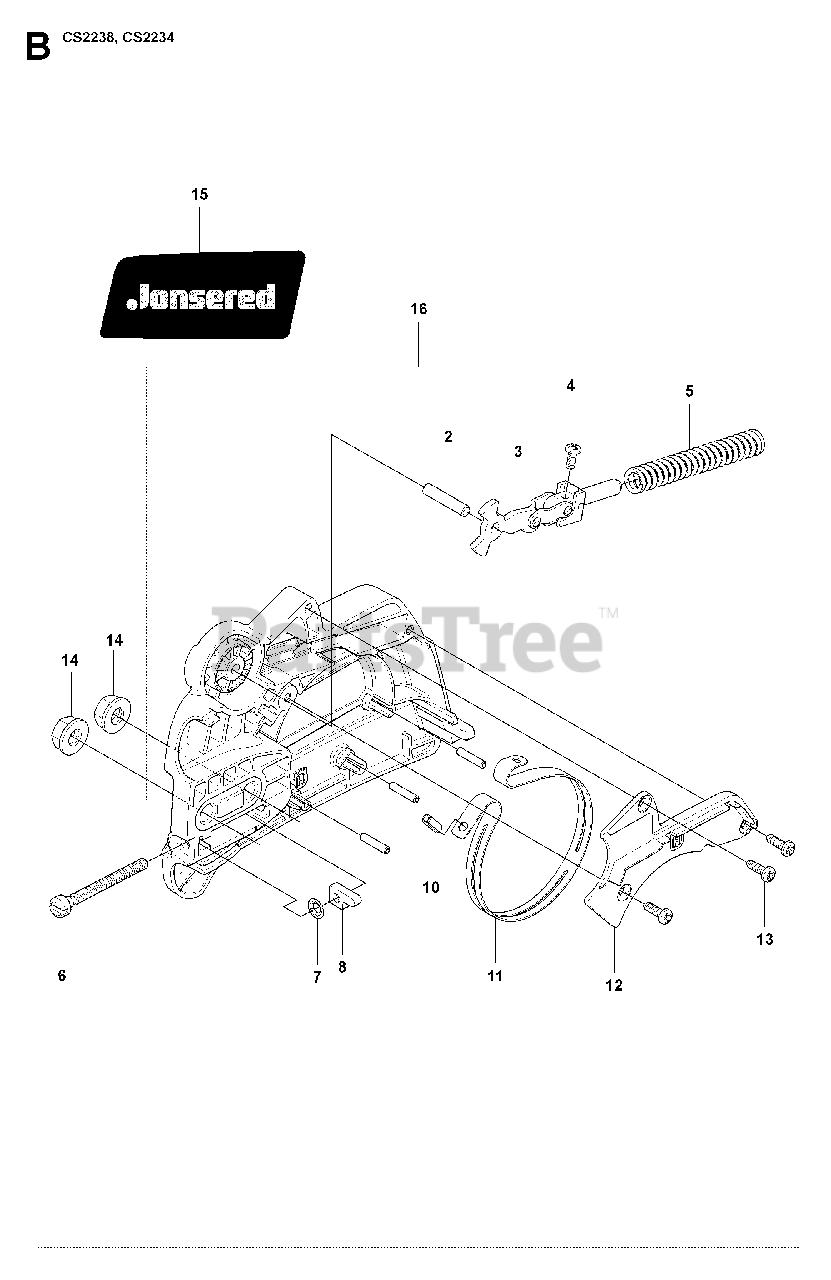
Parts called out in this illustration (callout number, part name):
2	PIN
3	FRONT LINK ASSY
4	SCREW
5	SPRING
6	SCREW
7	RETAINER
8	ADJUST PIN,BAR 36/41
10	PIN
11	BRAKE BAND
13	SCREW
